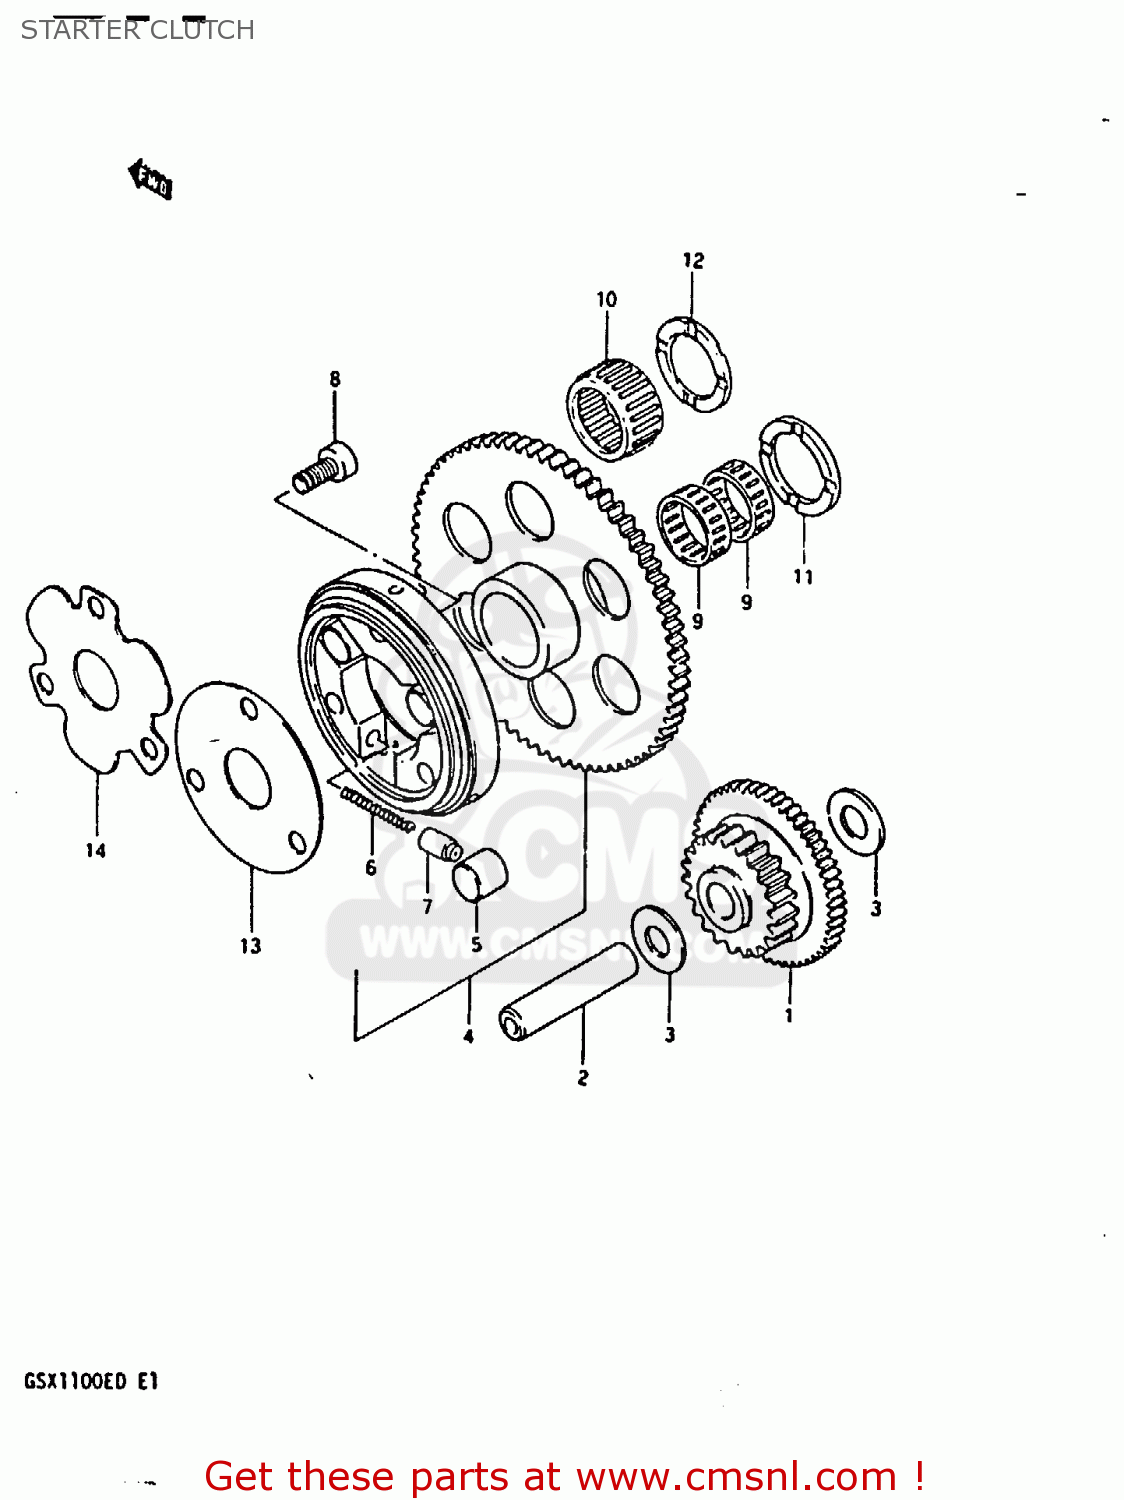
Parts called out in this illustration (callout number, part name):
1	GEAR,STARTER IDLE
2	PIN(7.4X13X56)
3	WASHER(13.3X25X0.85)
4	CLUTCH SET,STARTER
5	ROLLER(15X13)
6	SPRING
7	PIECE,PUSH
8	BOLT
9	BEARING
10	BEARING(29X35X24)
11	WASHER(25X38X2.5)
12	WASHER(29X41X2.5)
13	SHIM,STARTER CLUTCH HUB
14	SHIM,STARTER CLUTCH HUB
